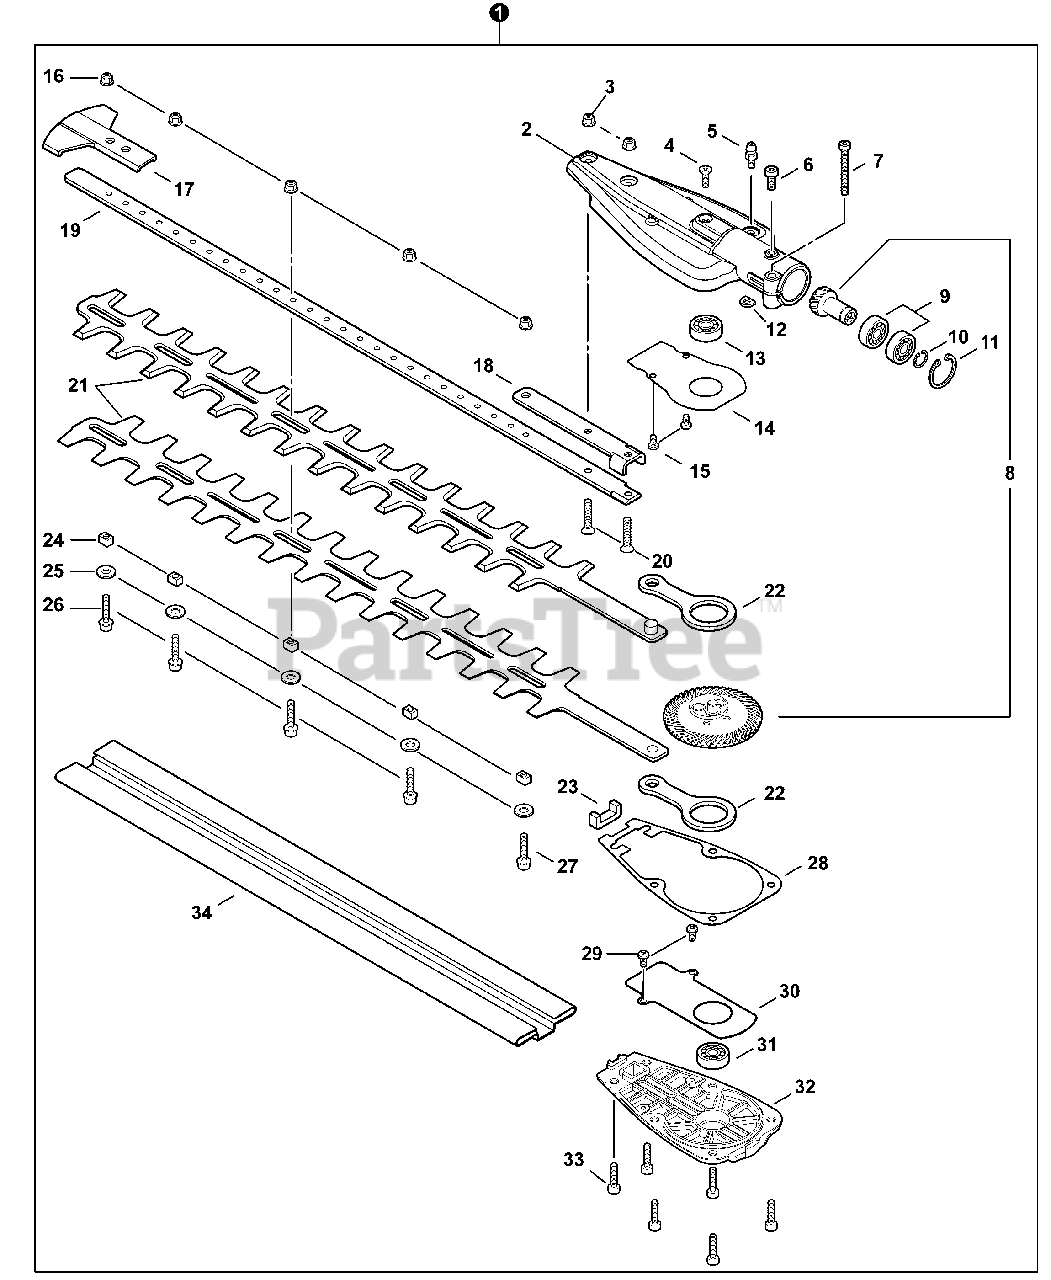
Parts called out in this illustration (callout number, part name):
1	HEAD KIT, TRIMMER
2	HOUSING, GEAR CASE
3	NUT, FLANGE M5
4	SCREW 5×5/8 HD-SOCKET
5	FITTING, GREASE
6	BOLT 5×12
7	BOLT 5×25
8	GEAR SET, BEVEL
9	BEARING, BALL
10	RING, SNAP 12
11	RING, RETAINING 24
12	D-WASHER
13	BEARING, BALL 608ZZ
14	PLATE, WEAR
15	SCREW 4×5
16	NUT, FLANGE M5
17	GUARD, TIP
18	SUPPORT, BLADE
19	SUPPORT, CUTTER
20	SCREW 5×18
21	BLADES, CUTTING
22	ROD, CONNECTING
24	GUIDE, BLADE 5
25	WASHER 5
26	BOLT 5×20
27	BOLT, FLANGE 5×22
28	GASKET, GEAR CASE
29	SCREW 4×5
30	PLATE, WEAR
31	BEARING, BALL - 628ZZ
32	COVER, GEAR CASE
33	BOLT 5×12
34	SCABBARD
